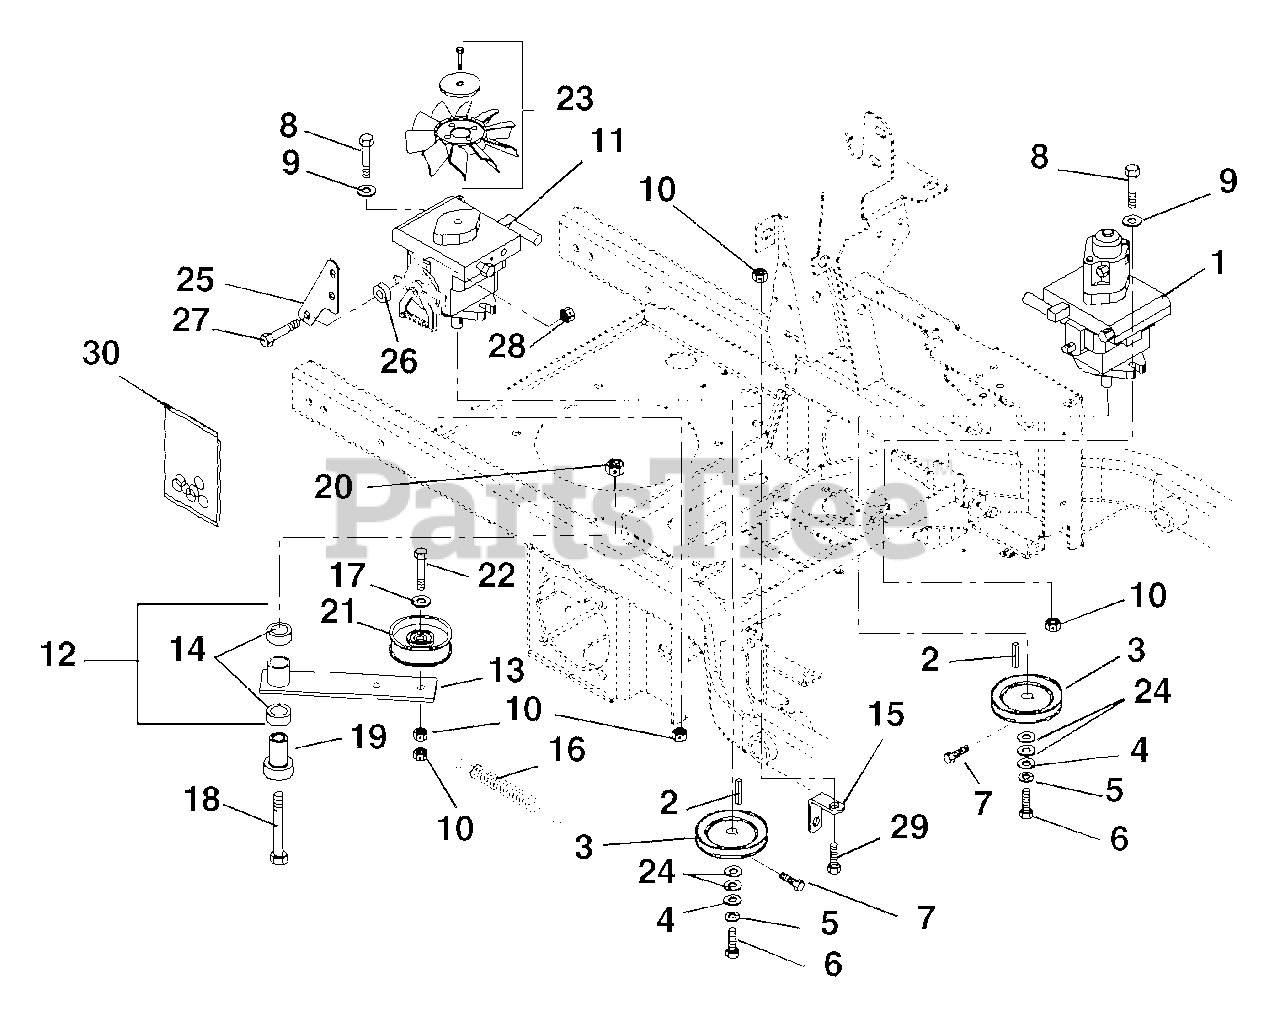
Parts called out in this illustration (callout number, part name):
1	PUMP, BDP-10A-801 (W/AUX)
2	KEY-STR 5MMX25MMX5MM
3	SHEAVE, PUMP .592 X 4.345
4	WSHR-FL-STL .281X1.000X.063
5	@WSHR-LK .25X.062 REG YWZC
6	BLT-HEX M6 X 1.0X12 YWZC
7	@BLT-HEX .25-20X.50 GR5 YWZC
8	@BLT-HEX .38-16X1.25 GR5 YWZC
9	WSHR-FL-STL .390X.75X.125 YWZC
10	@NUT-LK-TOP-FLG .38-16 YWZC
11	PUMP, BDP-10A-441 (THRU SHAFT)
12	ASSEMBLY,IDLER ARM GRD.DRIVE
13	WMT, IDLER ARM GROUND DRIVE
14	BRG, 1.00 X 1.12 X .75
15	ANCHOR - SPRING - IDLER
16	SPRING, EXTENSION
17	WSHR-FL-STL .390X.75X.125 YWZC
18	@BLT-HEX .50-13X3.50 GR5 YWZC
19	BEARING, PEDESTAL
20	@NUT-LK-TOP-FLG .50-13 YWZC
21	IDLER, FLAT 4.00X1.06
22	@BLT-HEX .38-16X2.25 GR5 YWZC
23	FAN, COOLING
24	@WSHR-FL-STL.656X1.31X.095 YWZ
25	BRACKET, RTN/DAMPER
26	SPACER .344X1.000X.375
27	@BLT-HEX .31-18X1.25 GR5 YWZC
28	@NUT-LK-TOP-FLG .31-18 YWZC
29	@BLT-HEX .38-16X.75 GR5 YWZC
30	KIT, PUMP SEAL
